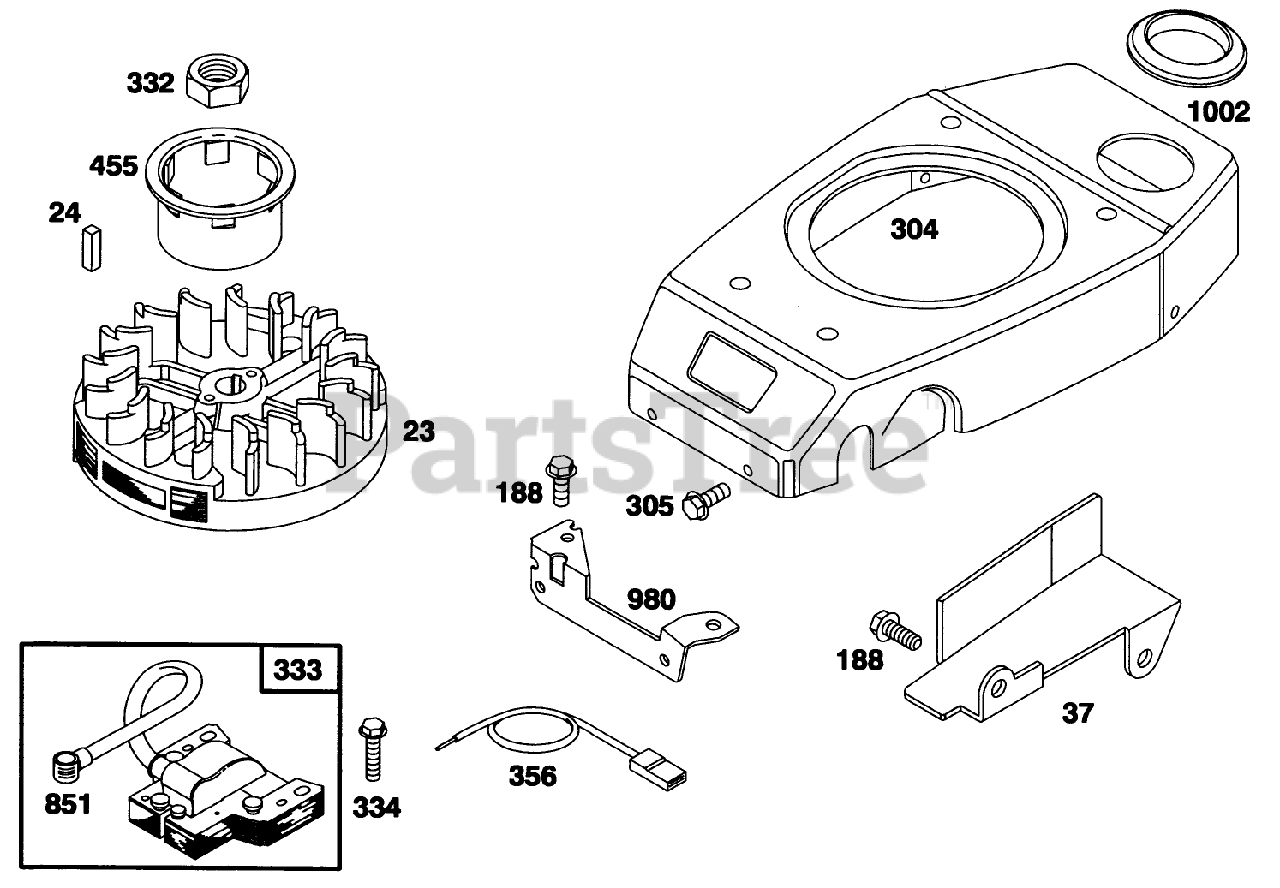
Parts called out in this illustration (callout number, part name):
24	KEY - FLYWHEEL
37	GUARD - FLYWHEEL
188	SCREW - SEM
304	HOUSING - BLOWER
305	SCREW - HEX HEAD
332	NUT - HEXAGON
356	WIRE - GROUND
980	BRACKET-BLOWER HSG
